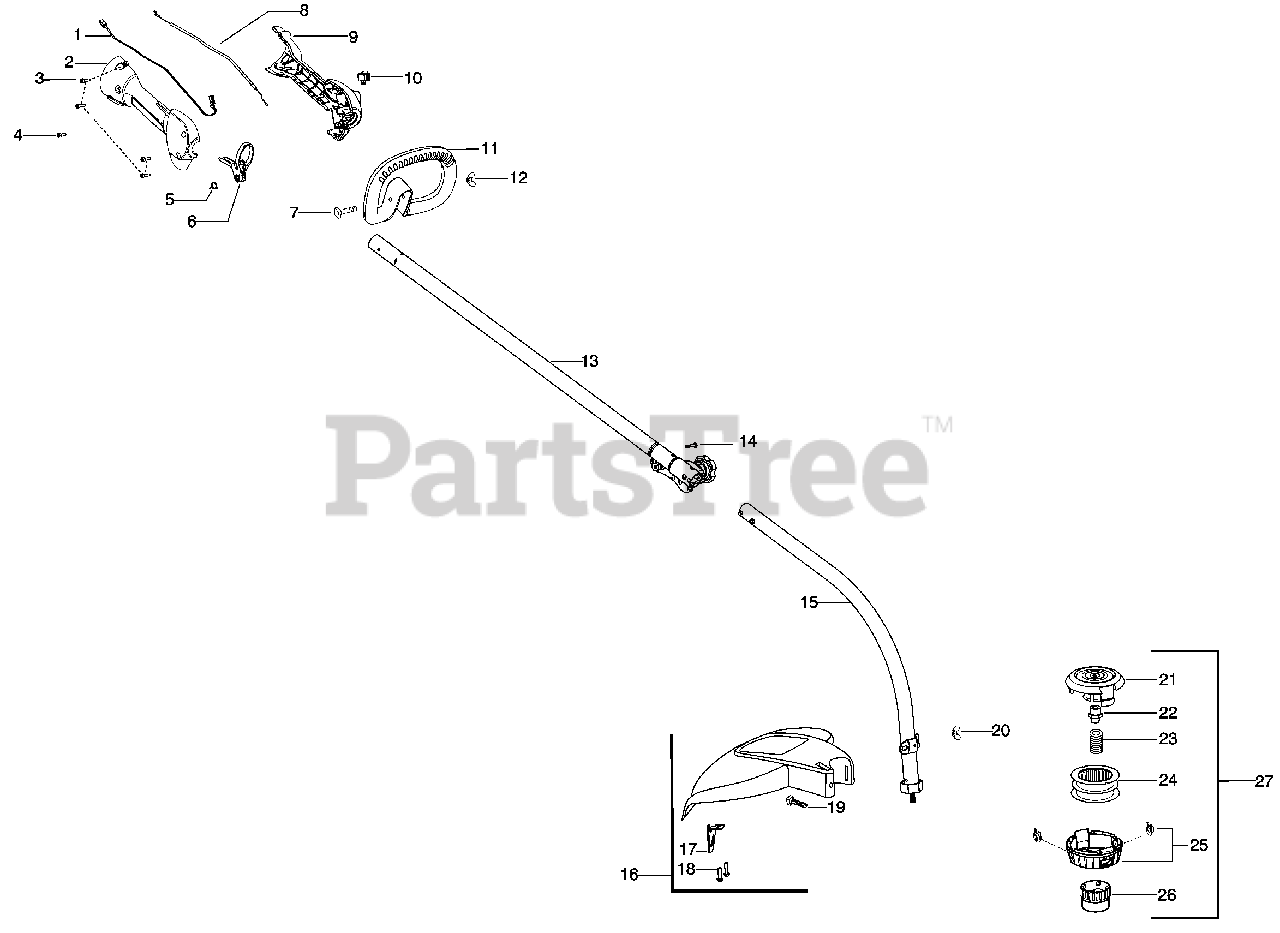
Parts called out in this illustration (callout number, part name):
1	Assy-Switch Wire
2	Housing-Throttle
3	Screw M4
4	Screw 10-14 x 1/2
5	Spring-Trigger
6	Kit - Trigger
7	Bolt - 1/4-20 x 2
8	Assy - Throttle Cable
9	Housing-Throttle
10	Kit-Switch
11	Assy - Handle Assist
12	Wingnut - 1/4-20
13	Kit-Driveshaft Upper
14	Screw - 12-24 x .480
15	Kit-Driveshaft Lower
16	Kit-Shield
17	Limiter-Line
18	Screw - 10-14 x 3/4
19	Bolt - 1/4-20 x 1-1/4
20	Wingnut - 1/4-20
24	Assy - Spool
25	Kit - Cover and eyelet
27	Accy - TNG 7 Cutting Head
